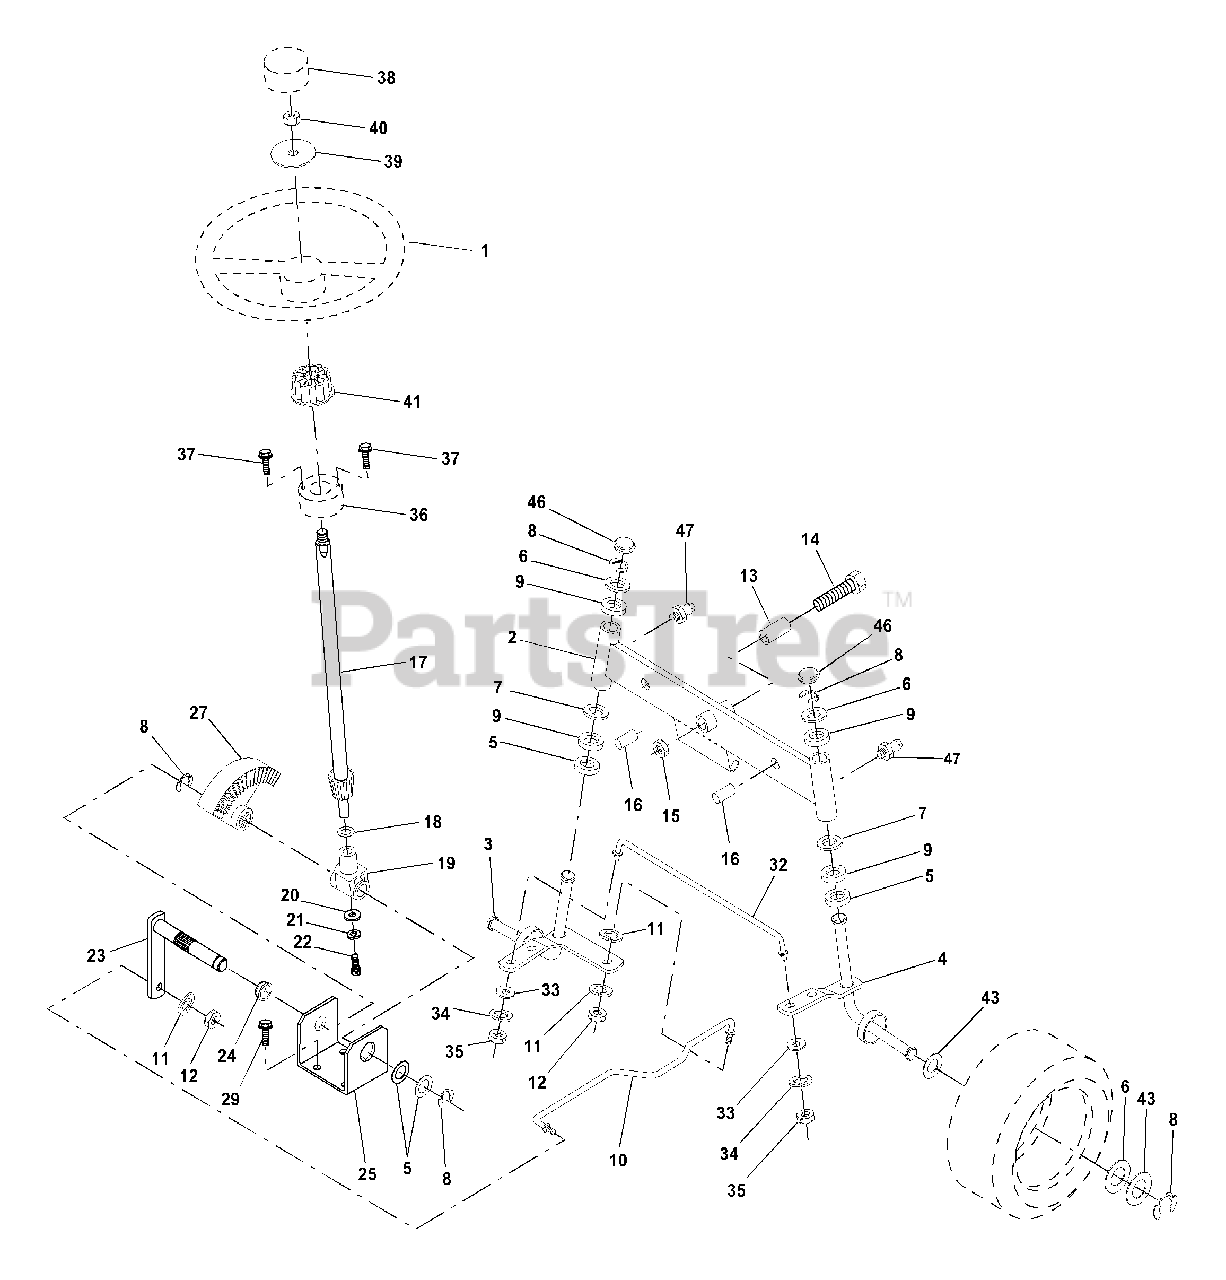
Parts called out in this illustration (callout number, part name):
1	Wheel Steering Auto Grey
2	Axle Asm Fr LT W/gzks 38/42
3	Spindle Asm LH
4	Spindle Asm RH
5	Bearing Race Thrust Harden
6	Washer 25/32 X 1-5/8 X 16 Ga
7	Washer 27/32 X 1-1/4 X 16 Ga
8	Ring Klip #t5304-75
9	Bearing Col Strg Blk
10	Link Drag Sol Ball Jt 20 064
11	Washer Lock Hvy Hlcl Spr 3/8
12	Nut Fin Hex 3/8-24 Unf
13	Spacer Bearing Axle Front
14	Bolt Hex 5/8-11 Unc X 3-1/2
15	Nut Lock Flange 5/8-11 Unc
16	Pin Axle 5/8 X 1 55/1 54 Lg
17	Shaft Asm Strg 20 31 x 3/4 YP YT
18	Washer Thrust 515x 750x 033
19	Support Shaft
20	Washer Shim 1/4 X 5/8 X 062
21	Washer Lock Hvy Helical 1/4
22	Screw Hex Socket 1/4-20 X 5/8
23	Shaft Asm Pittman
24	Nyliner Snap In
25	Bracket Steering
27	Gear Sector
29	Screw Thdrol 3/8-16x3/4 Ty-tt
32	Rod Tie Wire Form 19 75 Elec
33	Washer 11/32 x 3/4 x 16 Ga.
34	Washer, Lock Hvy Hlcl Spr 5/16
35	Locknut 5/16-24 Unf
36	Bushing Strg Blk 742/747 Id
37	Screw Slftp #10-16 X 1/2 Ty-b
38	Insert Cap Strg Wh Aut Hus Gry
39	Washer 53 X 2 25 X 160 Zinc
40	Nut Hex Jam Toplock 1/2-20 Unf
41	Adapter Wheel Strg 758/ 753id
43	Washer 25/32 X 1 1/4 X 16 Ga
46	Cap Spindle Fr Top Blk
47	Fitting Grease
